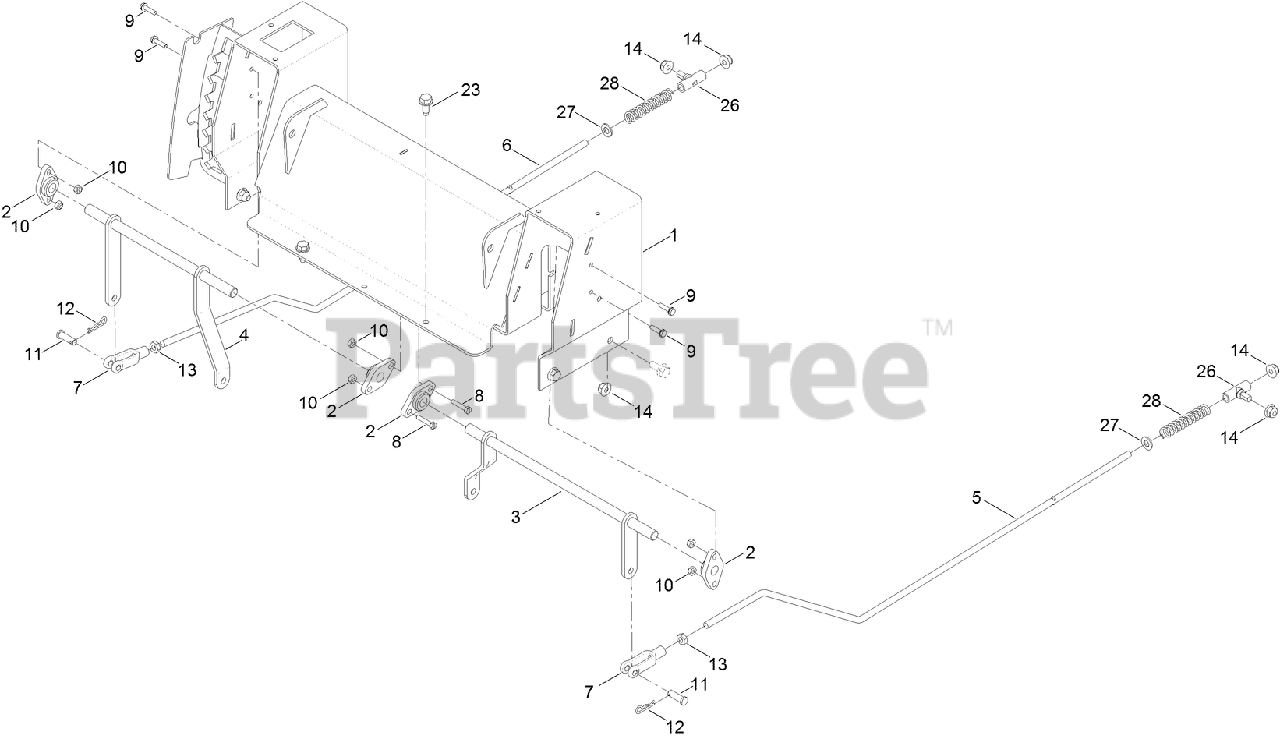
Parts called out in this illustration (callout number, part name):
1	CONTROL BOX ASM
2	BEARING-FLANGE
3	BELLCRANK-LH
4	BELLCRANK-RH, NARROW
4	BELLCRANK-RH
5	ROD-HYDRO, LH
6	ROD-HYDRO, RH
7	YOKE-ADJUSTABLE
9	SCREW-HWH
10	NUT-LOCK, NI
11	PIN-CLEVIS
12	PIN-COTTER
13	NUT-JAM
13	SCREW-HHF
14	NUT-HF, NI
23	SCREW-HWHTF
26	MOUNT-ROD, HYDRO
27	WASHER-PLAIN
28	SPRING-RETURN, NEUTRAL
